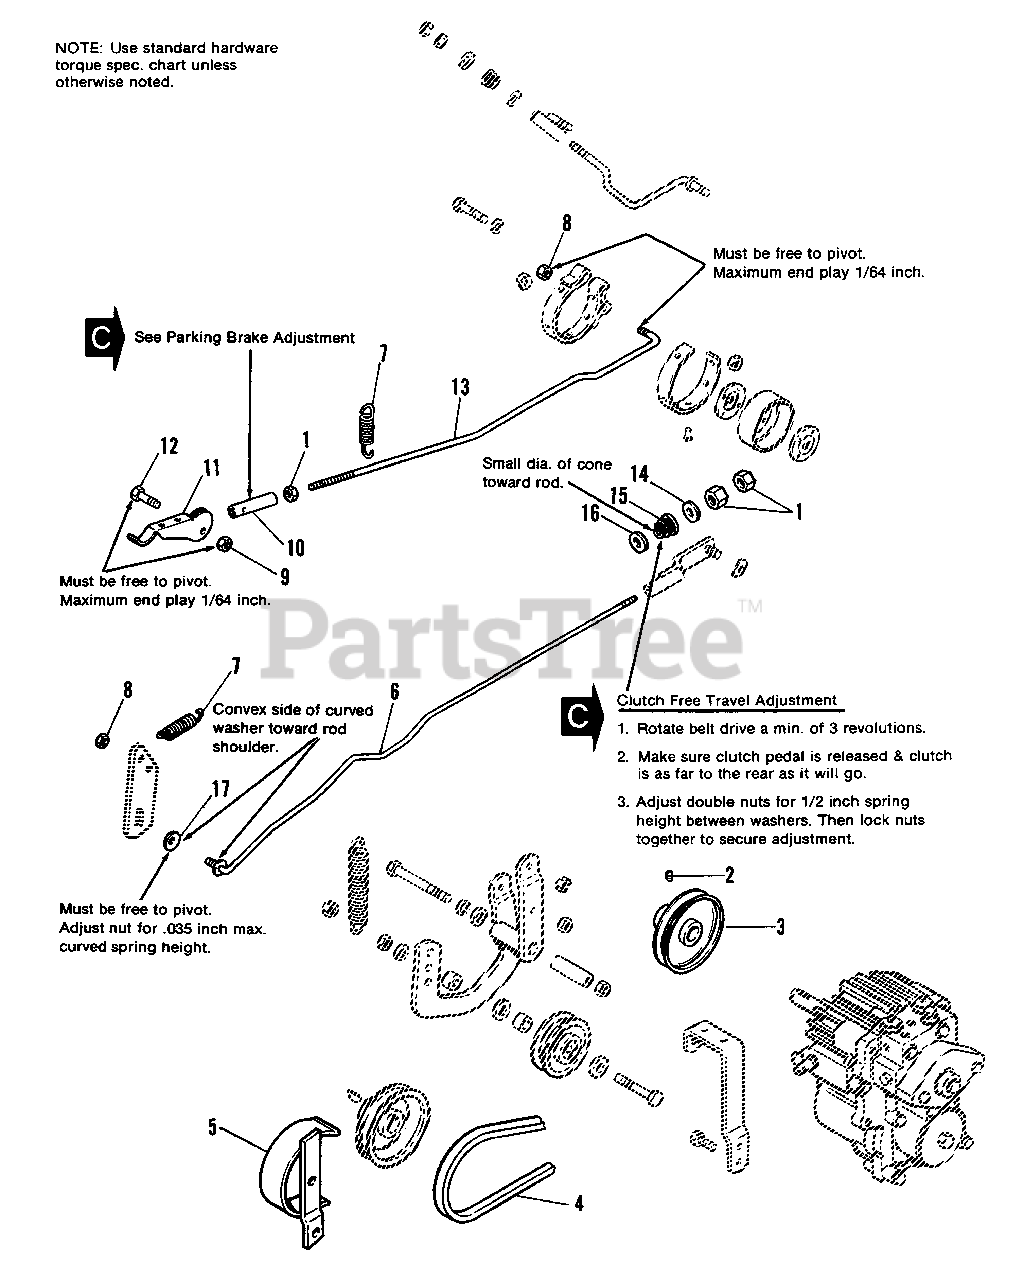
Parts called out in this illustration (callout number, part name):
1	NUT, Hex, Full, 5/16-18
2	SETSCREW, 5/16-18 x 3/8
3	PULLEY, Drive
4	V-BELT, Drive
5	GUARD ASSY.
6	ROD, Clutch
8	LOCKNUT, Hex, 5/16-18
9	LOCKNUT, Hex, 1/4-20
11	LEVER, Parking Brake
12	CAPSCREW, Hex Hd., 1/4-20 x 1
14	WASHER, 5/16
15	SPRING, Cone
17	WASHER, Curved, Spring
